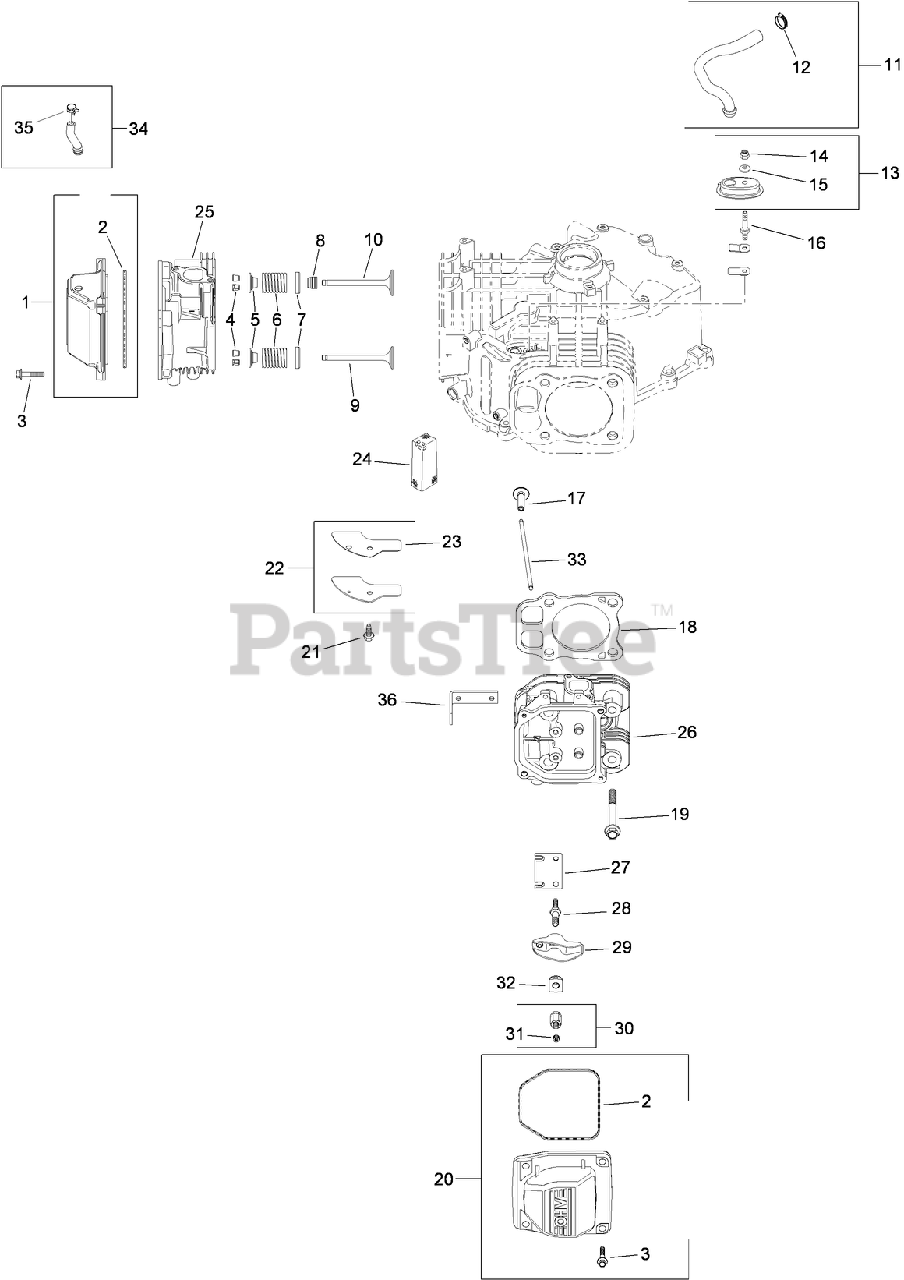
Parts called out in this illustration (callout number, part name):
1	BREATHER VALVE COVER KIT
2	O-RING
3	SCREW-FLANGE (M6X1.0X30)
4	RETAINER KIT
5	CAP-SPRING, VALVE
6	SPRING-VALVE
7	RETAINER-SPRING
8	SEAL-STEM, VALVE
9	VALVE-EXHAUST (STD)
10	VALVE-INTAKE (STD)
11	BREATHER HOSE KIT
12	CLAMP-HOSE, SPRING (1/2)
13	BREATHER HOUSING KIT (INCLUDES 15-16)
14	NUT-LOCK (M5X.8)
15	WASHER-SEALING
16	STUD-COVER, BREATHER
17	TAPPET KIT
18	CYLINDER HEAD GASKET KIT
19	SCREW-FLANGE (M10X1.5X90)
20	PLAIN ROCKER COVER KIT
21	SCREW-FLANGE, THREAD FORMING (M6X1.0X16)
22	BREATHER COVER KIT
23	GASKET-COVER, BREATHER
24	FILTER-BREATHER
25	CYLINDER HEAD NO.1 ASM
26	CYLINDER HEAD NO.2 ASM
27	PLATE-GUIDE
28	STUD-ROCKER
29	ARM-ROCKER
30	HEX NUT ASM (INCLUDES REF 32)
31	SCREW-SET
32	PIVOT-ARM, ROCKER
33	ROD-PUSH
34	FUEL PUMP HOSE W/CLAMP KIT (INCLUDES REF 36)
35	CLAMP-HOSE
36	STRAP-LIFTING
